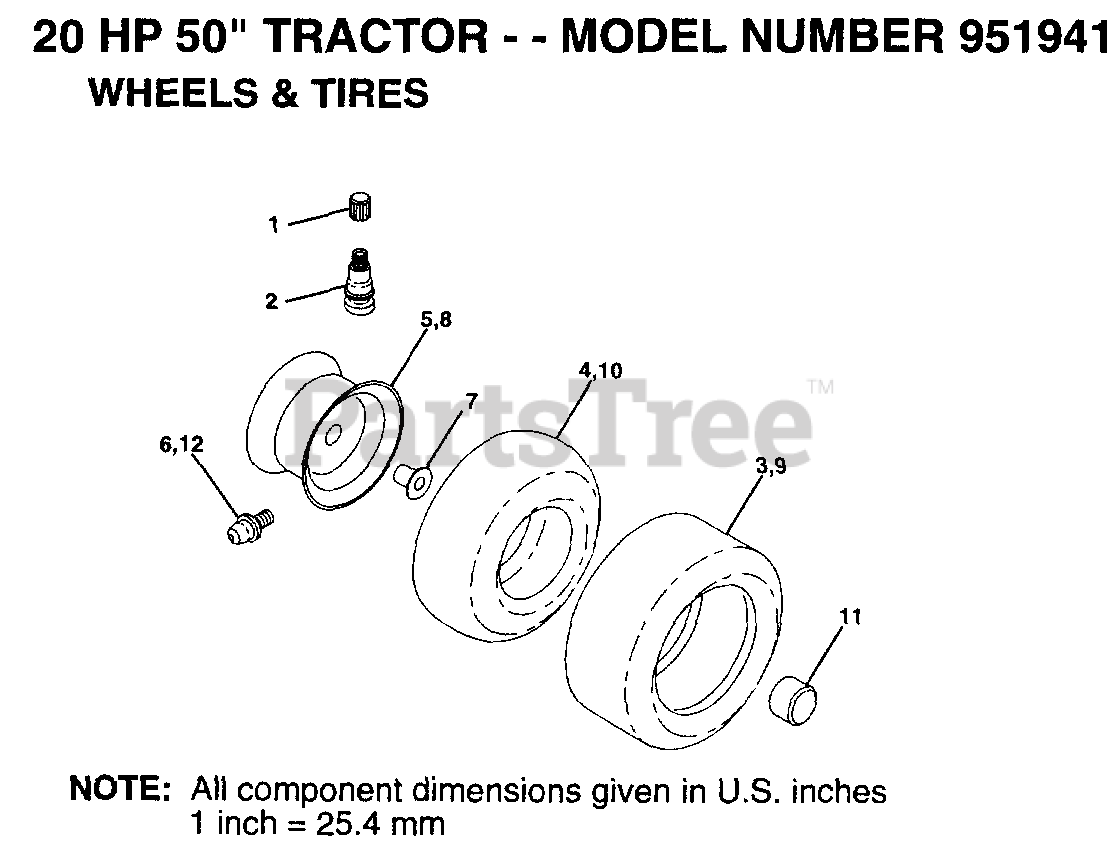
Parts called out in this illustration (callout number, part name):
1	VALVE CAP
2	VALVE STEM LT
4	TUBE.16X6.5/7.5-8
5	RIM.FRONT.
6	ZERK FITTING M
7	"FLANGE, BEARING"
8	"WHEEL,REAR"
10	TUBE.23X8/10-12
11	HUB CAP
12	FITTING LT
